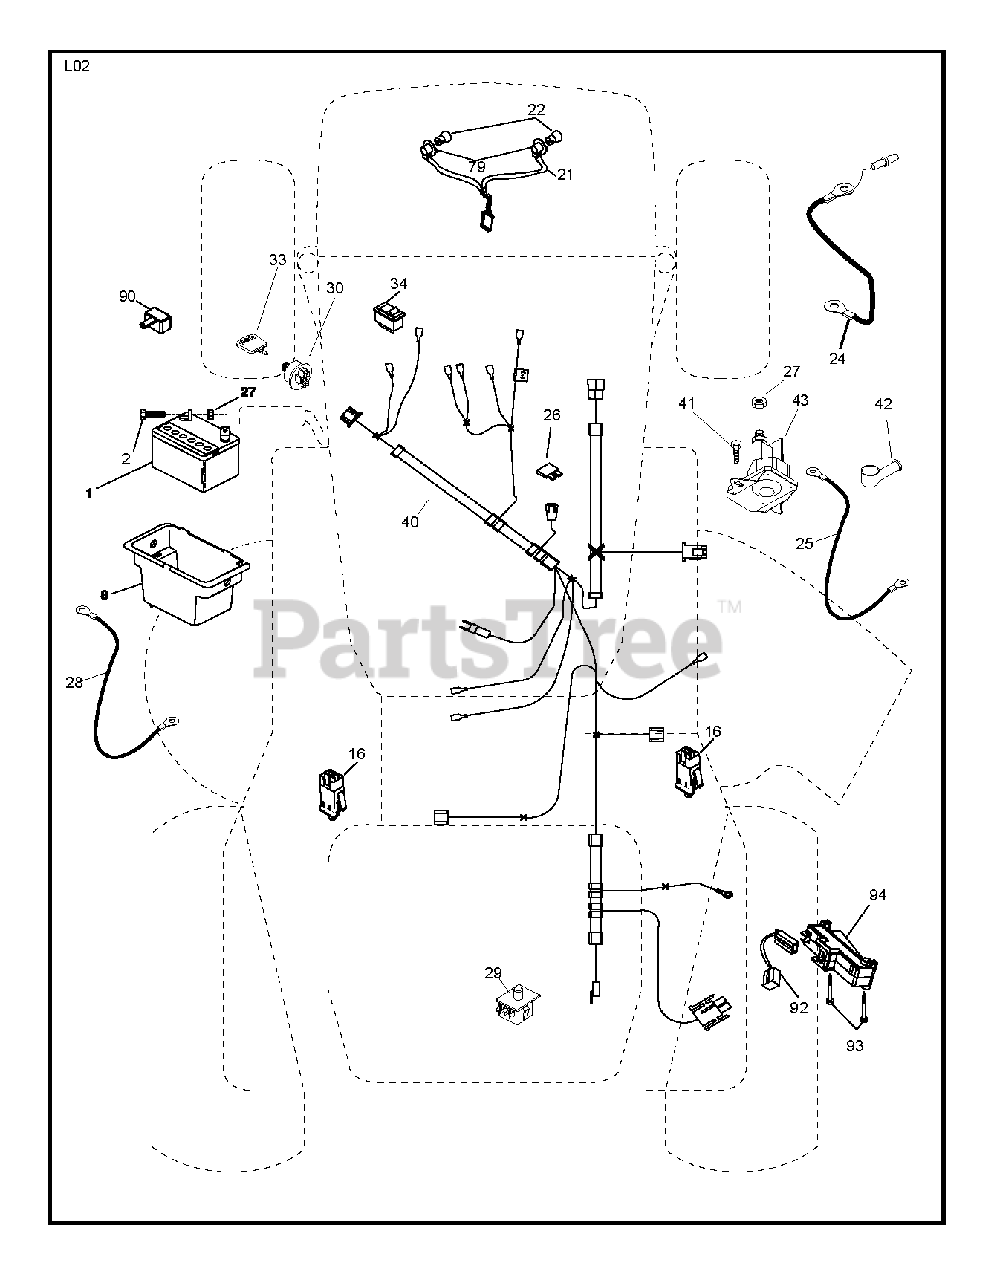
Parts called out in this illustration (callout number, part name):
1	REPL BY 532 12 38-99
8	BOX.BATTERY.FENDER
16	SWITCH INTERLOOK PUSH-IN
21	HARNESS ASSY LIGHT
22	LIGHTBULB
24	CABLE.GROUND.REAR.BTRY.8GA.44"
25	CABLE BATTERY 6 GA. 11" RED
26	FUSE 20AMP
27	NUT
28	CABLE GROUND 6 GA. 12" BLACK
29	SWITCH.SEAT.DP W/RAMPS
30	SWITCH.IGN.DELTA.W.LGH.ROS
33	KEY.CHAIN.BLISTER.PACK.GEN.INT
34	SWITCH LT
40	HARNESS.IGN.CABLE.REG.
42	TERMINAL COVER
43	SOLENOID.W/BRASS.PLUNG
79	BULB HOLDER ASM.
90	COVER.TERMINAL.BATTERY
92	HARNESS.PIGTAIL.CONSLE
93	SCREW.PLASTITE
94	MODULE.REVERSE.ROS
